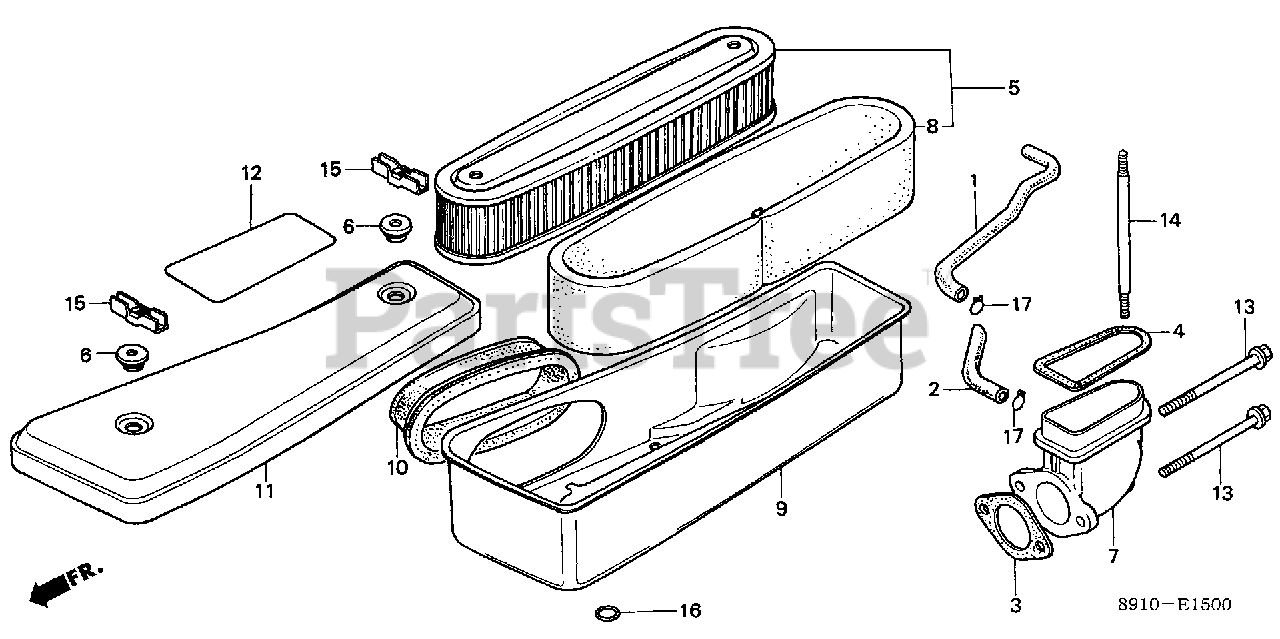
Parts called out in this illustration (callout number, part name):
1	TUBE, BREATHER (NOT AVAILABLE)
3	GASKET, AIR CLEANER
4	GASKET, AIR CLEANER ELBOW
5	ELEMENT, AIR CLEANER
6	WASHER, AIR CLEANER
7	ELBOW, AIR CLEANER
9	HOUSING, AIR CLEANER
9	HOUSING, AIR CLEANER *NH105* (MAT BLACK)
10	INLET, AIR
11	COVER, AIR CLEANER *NH105* (MAT BLACK)
13	BOLT, FLANGE (6X93)
14	BOLT, STUD (6X121)
15	NUT, AIR CLEANER COVER (DACRO COATING)
16	O-RING (5.1X2.2) (NOT AVAILABLE)
17	CLIP, TUBE (B12.5)
